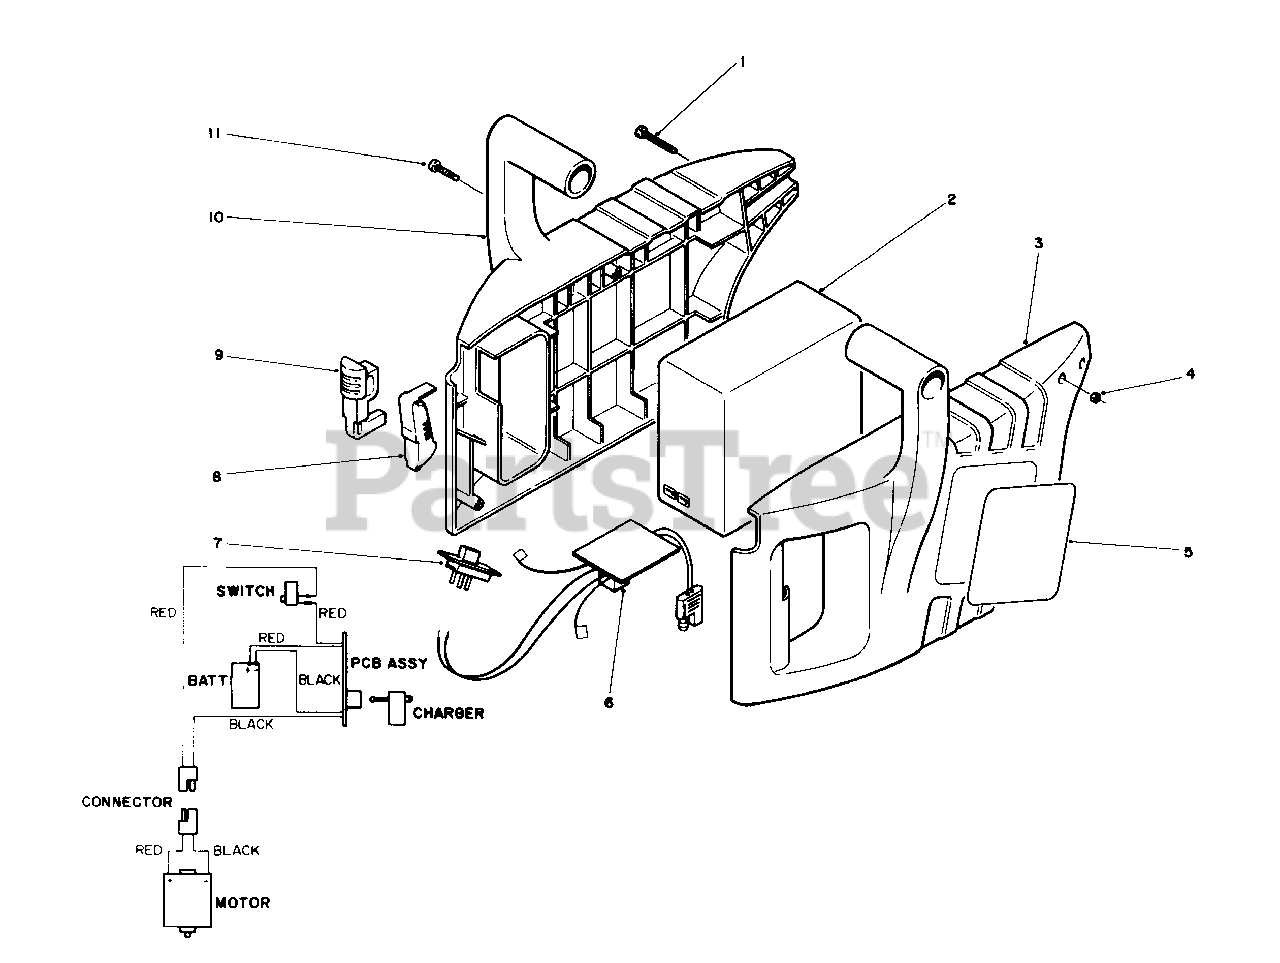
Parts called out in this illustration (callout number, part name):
1	Screw-Self Tapping
3	Handle & Battery Case R.H.
5	Decal-Toro
6	Wiring Harness
9	Lock-Trigger
10	Handle & Battery Case L.H.
11	Screw
